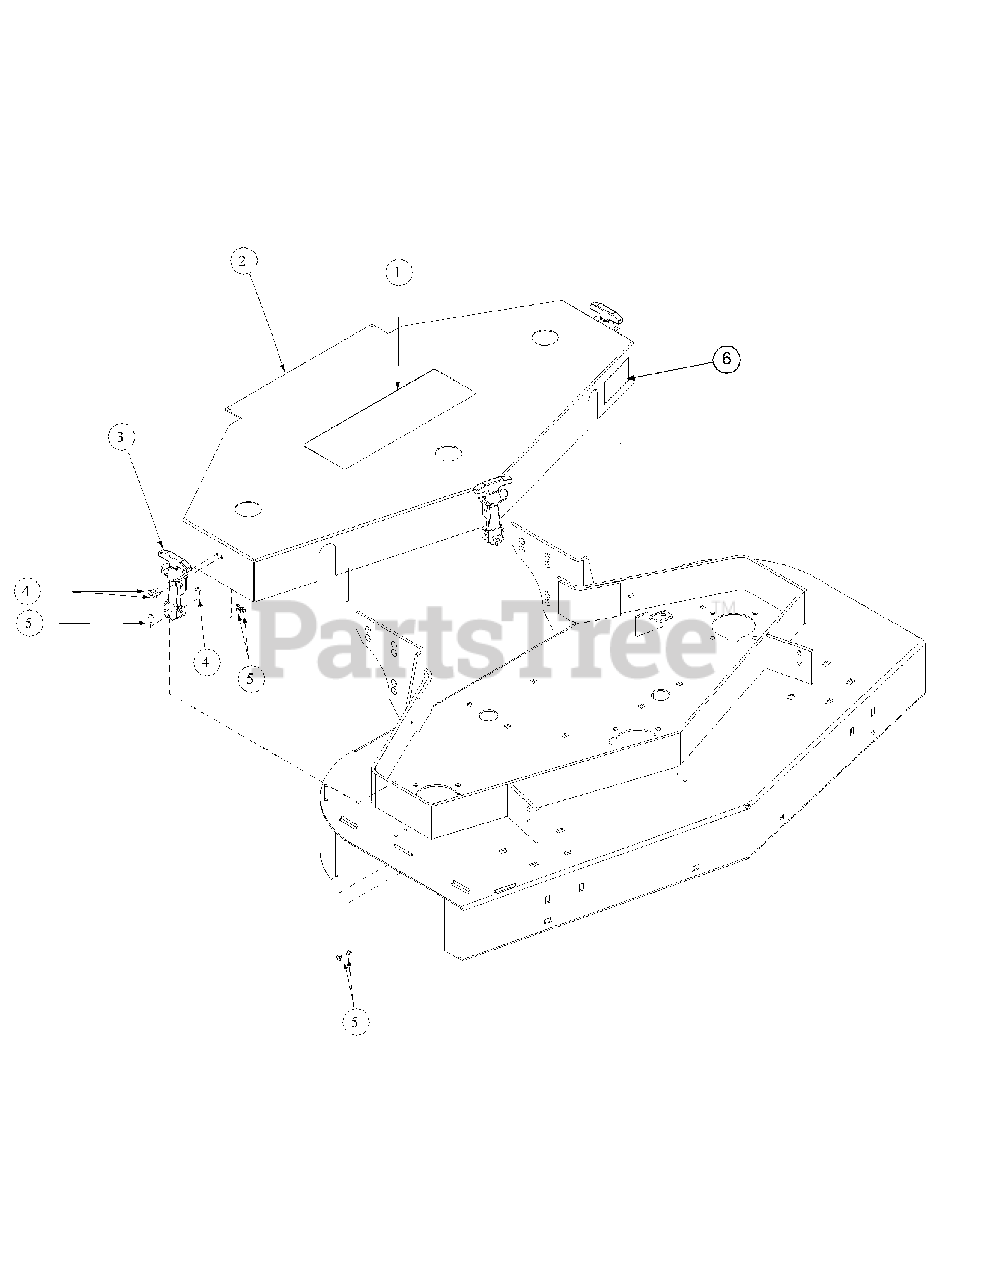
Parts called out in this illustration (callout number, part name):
1	Label Commercial Mower
2	Deck Cover 48"
3	Rubber Latch Hood
4	Machine Screw, 10-24 x 1/2
5	Lock Nut, Nylon Insert, #10-24
6	Label, H1548
